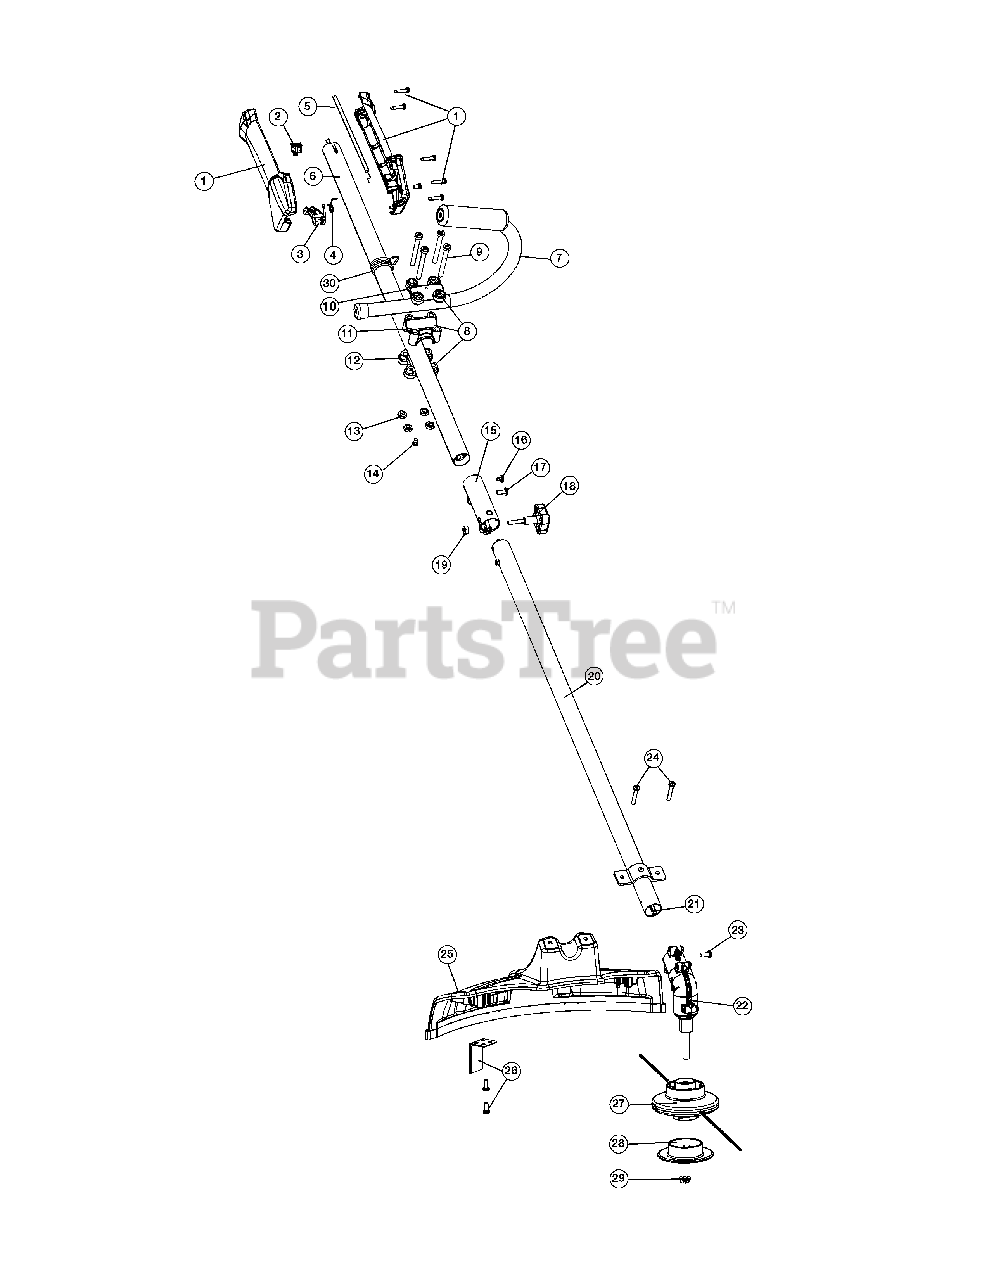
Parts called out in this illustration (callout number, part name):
1	Throttle Housing Assembly (Incl. 2-4)
3	Throttle Trigger
4	Throttle Trigger Spring
5	Throttle Cable
6	Upper Driver Shaft Housing Assembly
7	J-Handle Assembly
8	Handle Bracket Assembly
10	Upper Handle Clamp
11	Middle Handle Clamp
12	Lower Handle Clamp
14	Anti-Rotation Screw
15	Split Boom Coupler (Incl. 16-19)
18	Adjustment Knob (Incl. 19)
19	Knob Retaining Nut
20	Lower Driver Shaft Housing Assembly
21	Lower Flexible Drive Shaft
22	Gearbox Assembly
23	Anti-Rotation Screw
24	Shield Mounting Hardware
25	Shield Assembly (Incl. 26)
26	Blade Assembly
27	Fixed Line Head Assembly (Incl. 28 & 29)
30	Shoulder Strap Clip
